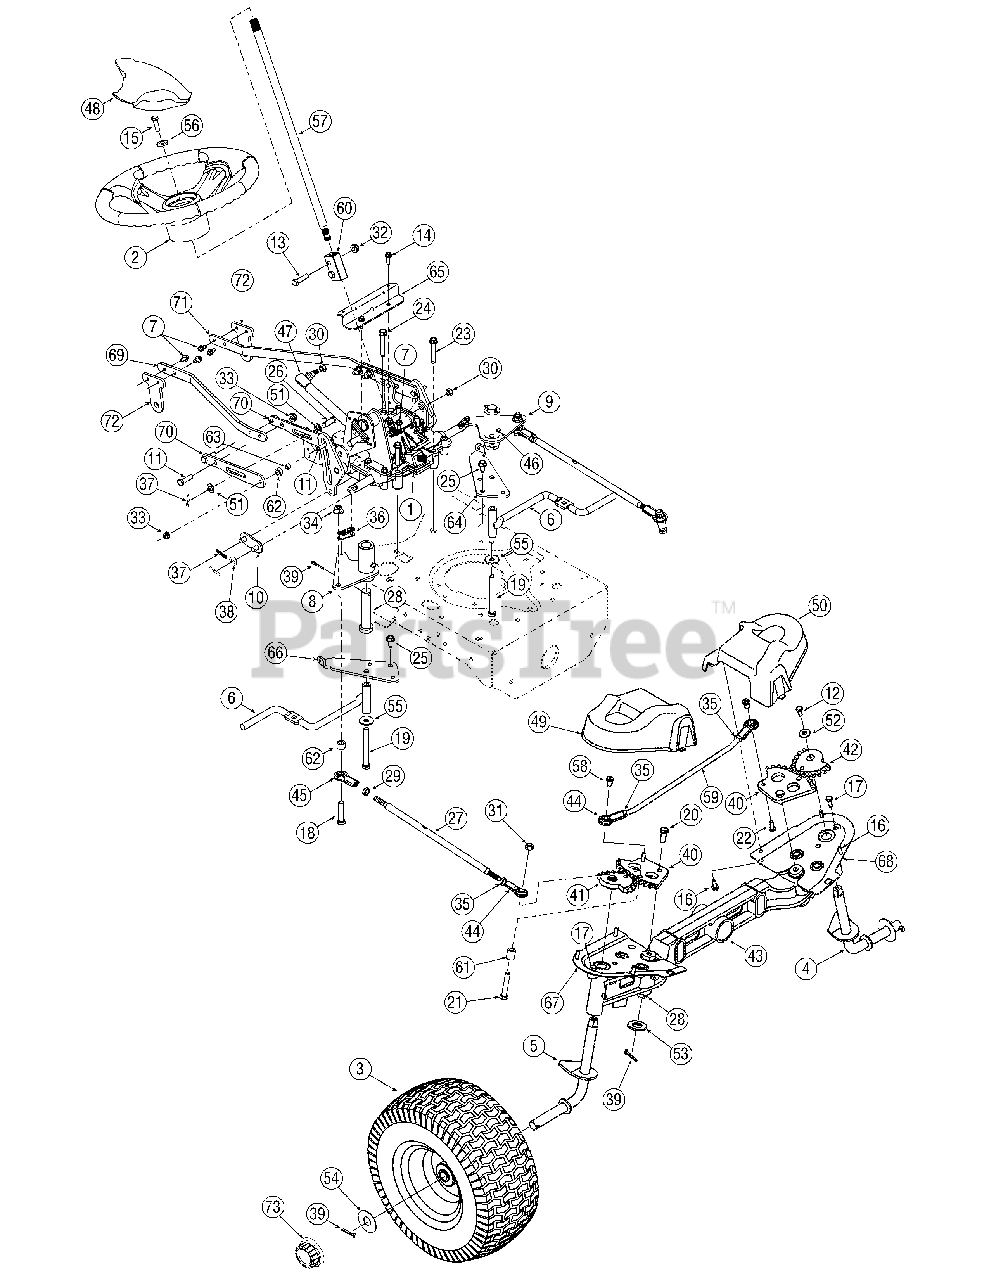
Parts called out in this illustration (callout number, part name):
1	Steering Assembly, Steering/Hydro
1	Kit, Replacment Steering Gear Box
2	Wheel, Steering
3	Wheel Assembly
7	Screw, Hex Wash Hd. Tapp, 1/4-20 x .5
8	Arm, Steering, RH
8	Service Kit RH
9	Arm, Steering, LH
9	Service Kit LH
10	Link, Steering Box/Hydro
11	Screw, Hex Cap, 1/4-20 x 1.0 Gr5
12	Screw, Hex Cap, 1/4-28 x .625 Gr5
13	Screw, Hex Cap, 5/16-18 x 1.25 Gr5
14	Screw, Hex Wash Hd. Tapp, 1/4-20 x .75
15	Screw, Hex Wash Hd. Tapp, 5/16-18 x .875
16	Screw, Hex Wash Hd. Hi/Lo, 1/4-15 x .5
17	Screw, Hex Cap, 1/4-20 x .75 Gr5
18	Screw, Hex Cap, 3/8-16 x 1.5 Gr5
19	Screw, Hex Cap, 3/8-16 x 3.5 Gr5
20	Screw, Hex Cap Lock, 3/8-16 x .75 Gr5
21	Screw, Hex Cap, 3/8-16 x 2.0 Gr5
22	Screw, Hex Cap Lock, 1/4-20 x .75 Gr5
23	Screw, Hex Wash Hd. Tapp, 5/16-18 x 2.0
24	Screw, Hex Wash Hd. Tapp, 5/16-18 x 2.25
25	Screw, TT, 5/16-18 x .75
26	Pin, Clevis, .375 x .969 HT
27	Link, Drag
28	Shaft, Steering Pivot Gear
29	Nut, Jam, 3/8-24 LH Thrd
30	Nut, Hex Lock, M8 x 1.25 Gr9
31	Nut, Hex Lock, 3/8-16
32	Nut, Hex Insert Flange Lock, 5/16-18 GrF
33	Nut, Hex Insert Flange Lock, 1/4-20 GrF
34	Nut, Hex Insert Flange Lock, 3/16-16 GrF
35	Nut, Hex Jam, 3/8-24 Gr2
36	Link, Connnecting
37	Pin, Internal Cotter
38	Washer, Sping, .39 x .75 x .010
39	Pin, Cotter, 5/32 x 1.25
40	Gear, Spur, 12T
41	Gear, Spur, RH 13T
42	Gear, Spur, LH 13T
43	Axle, Pivot Bar
44	End, Ball Joint Rod
45	End, Ball Joint Rod, LH Thrd.
46	Fitting, Grease
47	Cylinder, Damper
48	Cover, Steering Wheel
49	Cover, Steering Gear, RH
50	Cover, Steering Gear, LH
51	Washer, Flat, .375 x .738.063
52	Washer, Bell, .265 x .75 x .062
53	Washer, Flat, .76 x 1.5 x .12
54	Washer, Flat, .755 x 1.92 x .060
55	Washer, Bell, .396 x 1.14 x .095
56	Washer, Flat, .406 x .875 x .105
57	Shaft, Steering, .625 x 17.281
58	Nut, Shoulder, .375 x .5
59	Rod, 3/8-24 x 14.4 Lg
60	Block, Steering Shaft
61	Spacer, .385 x .63 x .75
62	Spacer, .380 x .625 x .265
63	Spacer, .26 x .372 x .33
70	Bracket, Hydro/Steering Adjustment
73	Hub Cap
74	Washer, Lock
